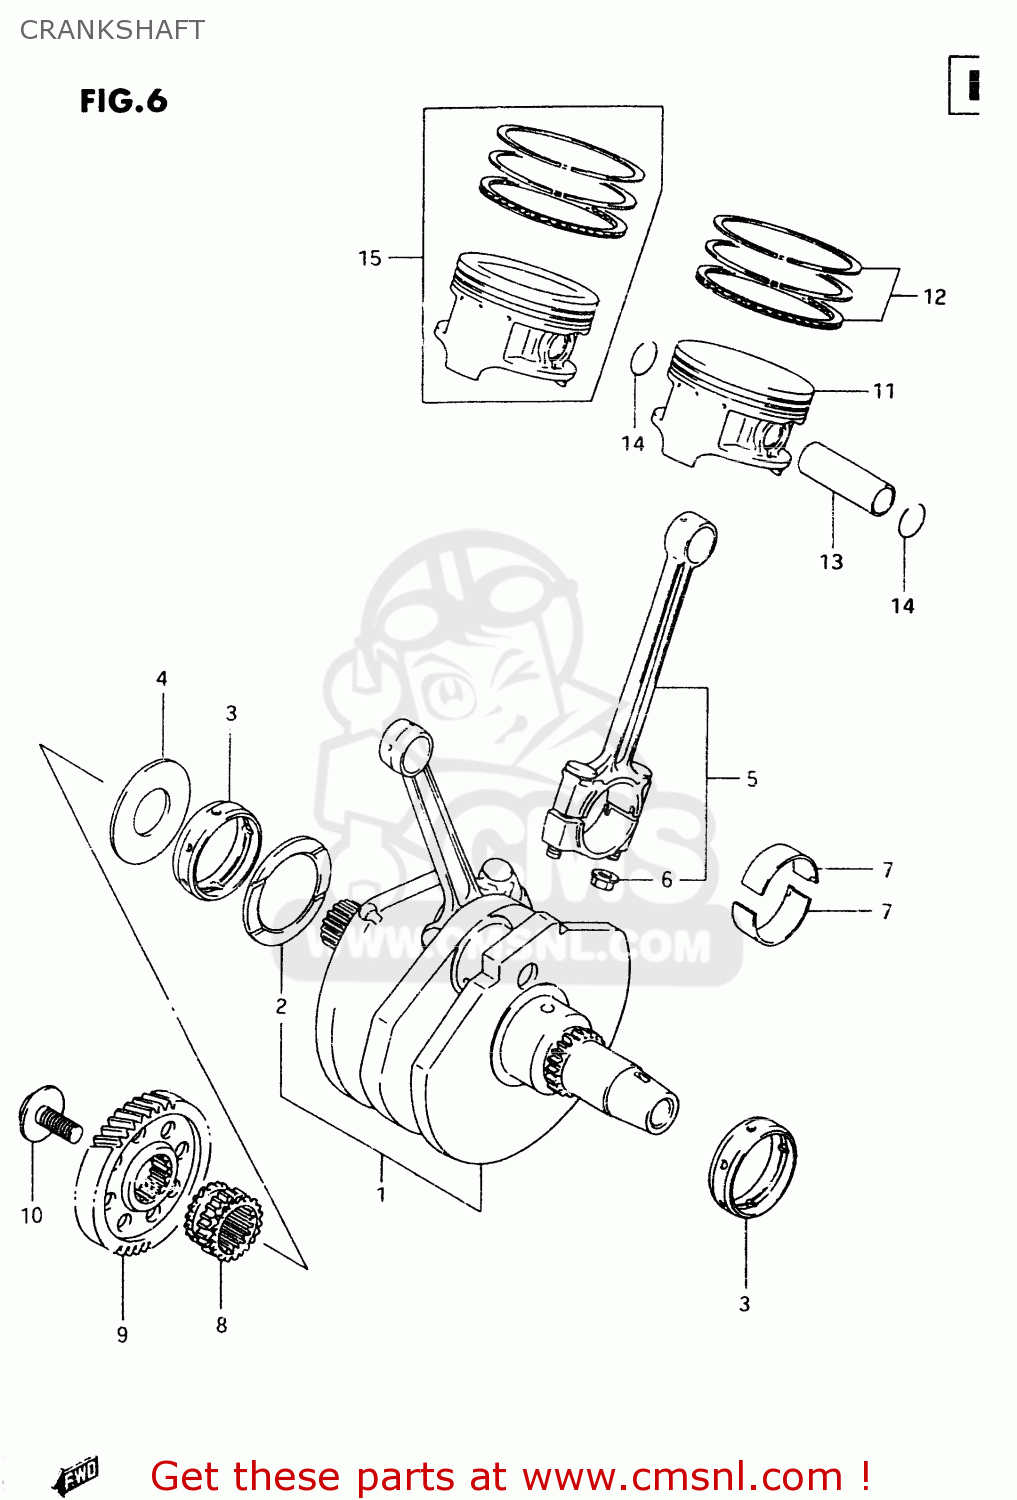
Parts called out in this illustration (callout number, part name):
1	CRANKSHAFT SET
2	WASHER(48.1X64X1.94)
3	METAL,CRANKSHAFT
4	WASHER,CRANK THRUST
5	CONNECTING ROD ASSY
6	NUT
7	BEARING,CRANK PIN
8	SPROCKET,CAM CHAIN DRIVE,R
9	GEAR,PRIMARY DRIVE
10	BOLT(12X28)
11	PISTON
12	RING SET,PISTON
13	PIN,PISTON
14	CIRCLIP,PISTON PIN
15	PISTON SET(OS:0.5)
